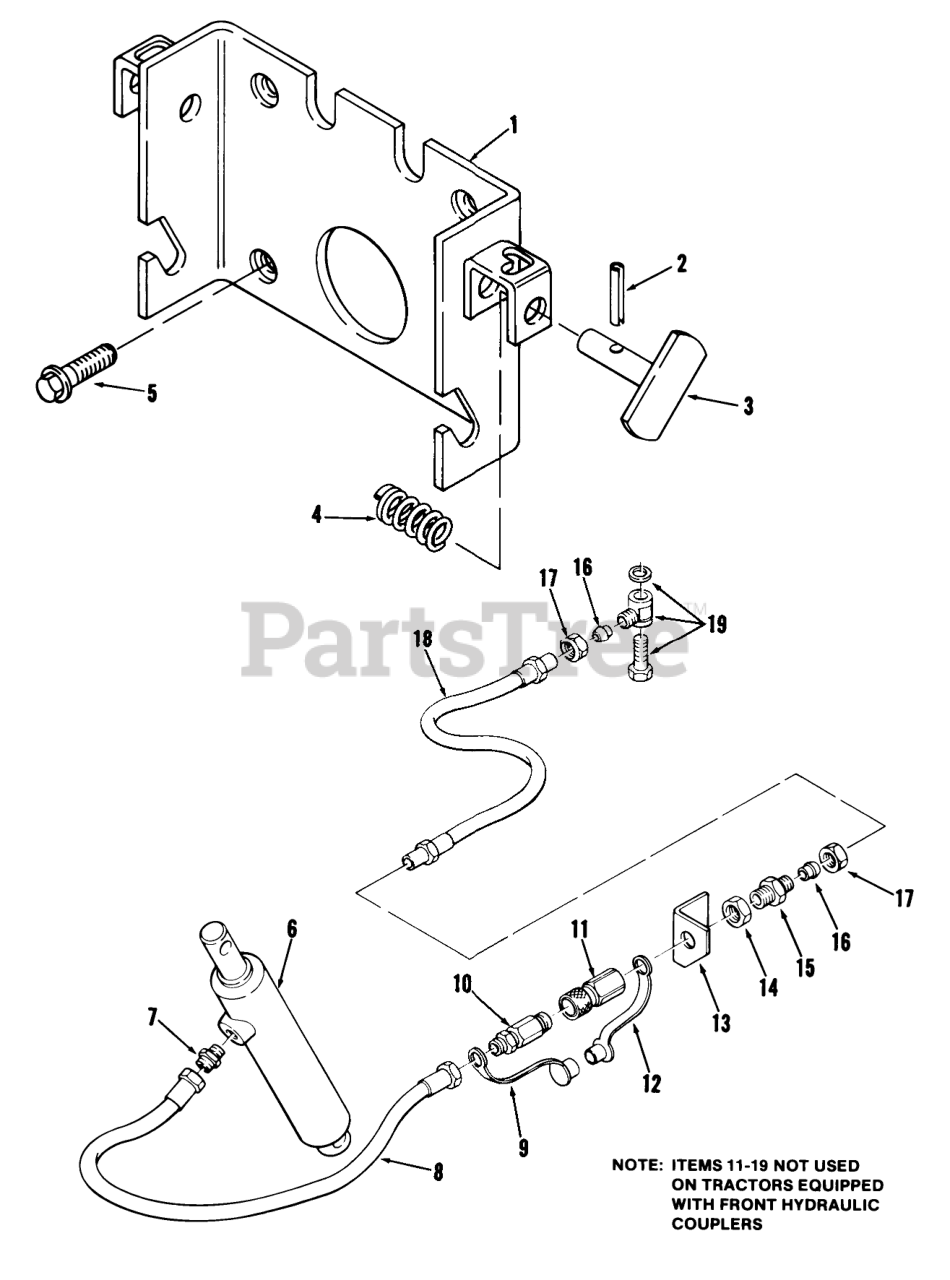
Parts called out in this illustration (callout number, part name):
1	Mounting Plate
2	Rollpin
3	Locking Pin
4	Spring
6	Hydraulic Cylinder
7	FITTING
8	Hydraulic Hose
9	DUST CAP
10	Coupling Plug
11	Q.D. Fitting
12	Dust Cap
13	Mounting Plate
15	Fitting
16	RING SEAL
19	JOINT (CONSISTS 2 PT
